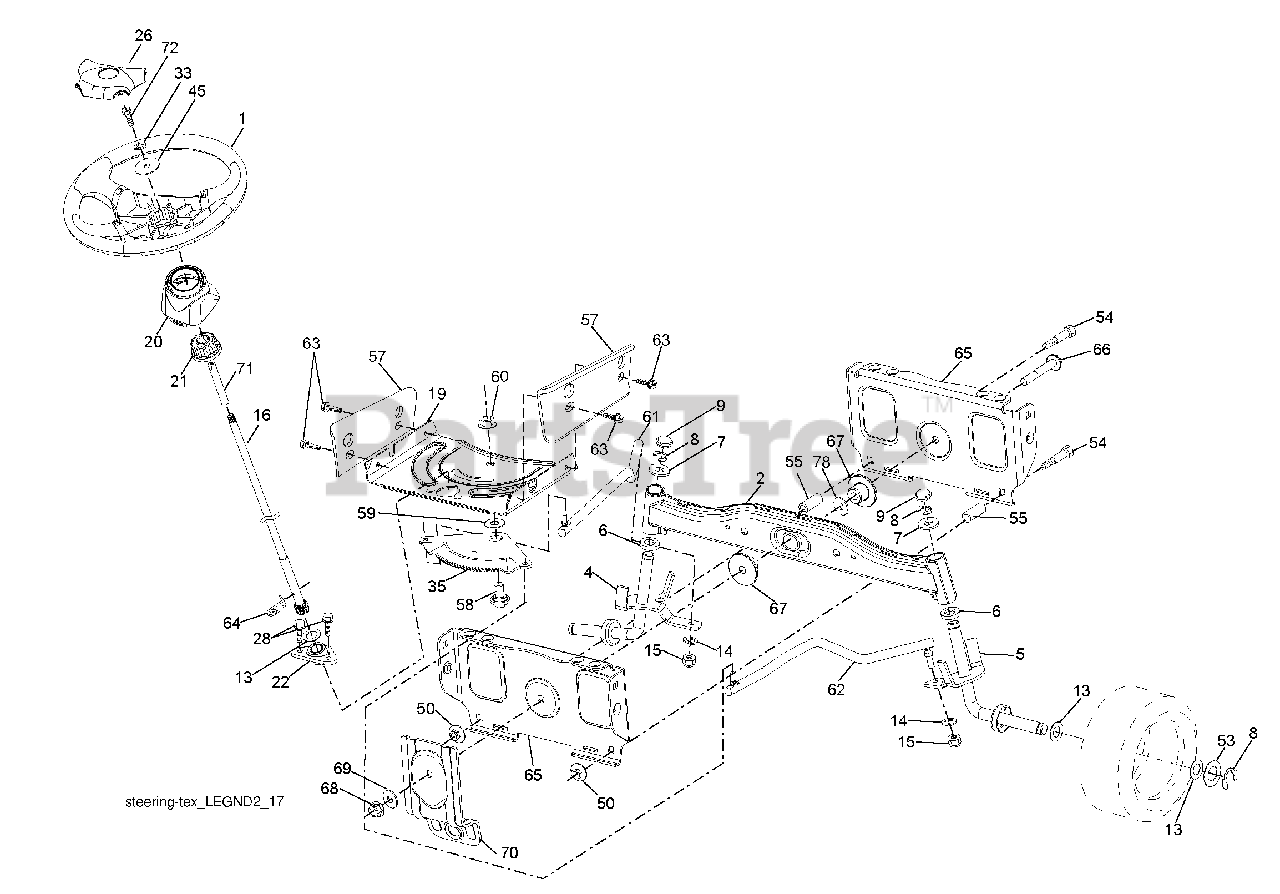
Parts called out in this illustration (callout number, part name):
1	Wheel, Steering
2	Axle Asm., Front
4	Spindle Asm., LH
5	Spindle Asm., RH
6	Bearing, Race Thrust Harden
7	Washer 25/32 x 1-5/8 x 16 Ga.
8	Ring, Clip #T5304-75
9	Cap, Spindle
13	Washer 25/32 x 1-1/4 x 16 Ga.
14	Washer, Lock Hvy Hlcl Spr 3/8
15	Nut, Crown Lock 3/8-24 unf
16	Shaft Steering
19	Plate Steering
20	Boot, Steering
21	Adapter, Wheel Steering
22	Bushing, Strg. Blk
26	Insert, Wheel Steering
28	Screw 3/8-16 x 3/4
33	Washer Lock 5/16
35	Gear, Sector Plate
45	Washer 11/32 ID x 2-3/8 x 12 Ga.
50	Nut Lock 3/8-16
53	Washer Hardened .793 x 1.637 x .060
54	Bolt 3/8-16 x 2-1/4
55	Spacer Brace Axle
57	Bracket Upstop
58	Bolt Shoulder Sector Pivot CFM
59	Washer Thrust Sector Steering
60	Nut Flange Lock 5/8-11
61	Draglink LH
62	Draglink RH
63	Screw 5/16-18 x 3/4
64	Retainer Clip Spring Steering
65	Brace Axle Front
66	Bolt Hex Fghd 7/16-14 x 3 Serr
67	Bushing PM Front Axle
68	Nut Lock Flange 7/16-14 Gr. 5
69	Washer 1.5 x .505 x .118
70	Bracket Deck Susp. Front
71	Shaft Exten Strg.
72	Bolt Fin Hex 5/16-18 unc x 4.5 Gr. 5
78	Washer Thrust .515 x .750 x .033
